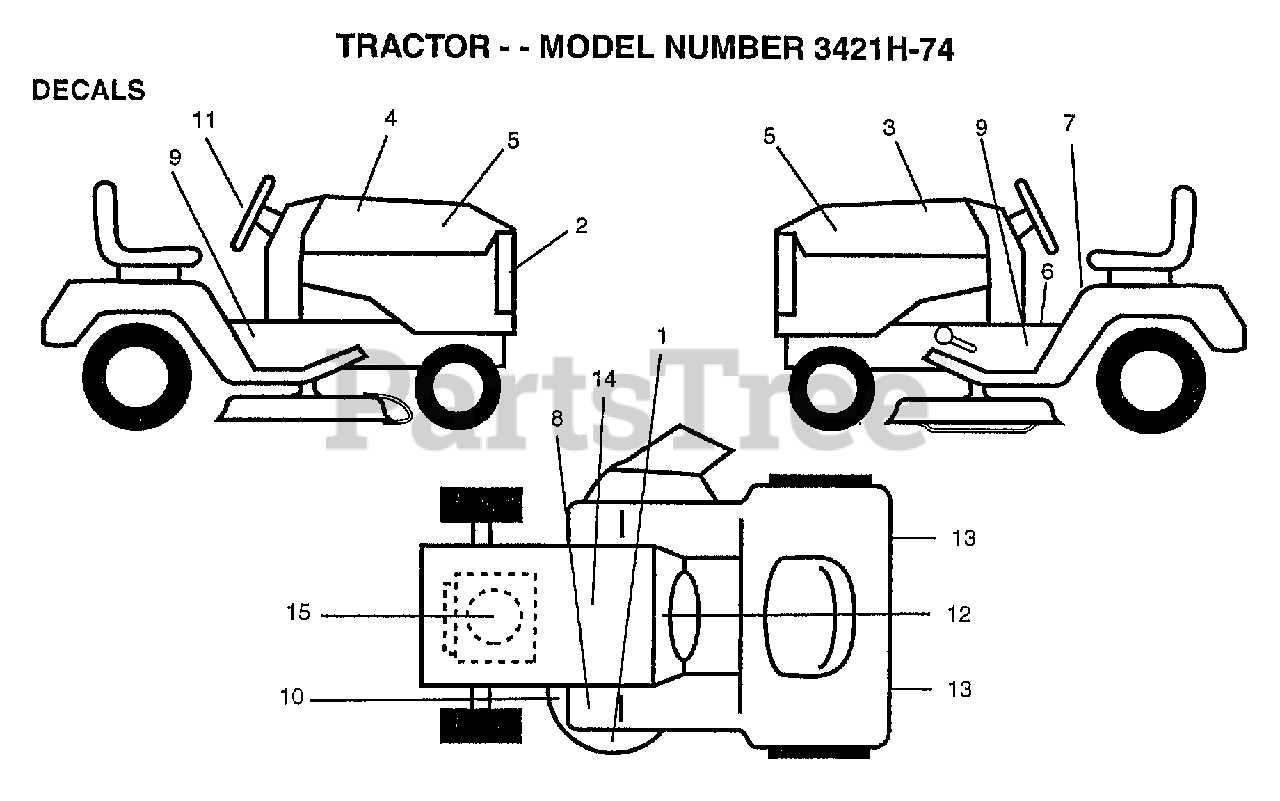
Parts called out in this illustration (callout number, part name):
2	GRILL DECAL
3	"DECAL.HOOD,LH"
4	"DECAL HOOD,RH"
5	NAMEPLATE LOGO
6	DECAL BRAK PARK
7	"DECAL DANGER,FEND"
9	DECAL-CHASSIS
10	DECAL
12	"DECAL-INST,OPER"
13	REFLECTOR-TAIL YT
14	DECAL.BATRY.3-3908
15	DECAL, HP ENGINE
